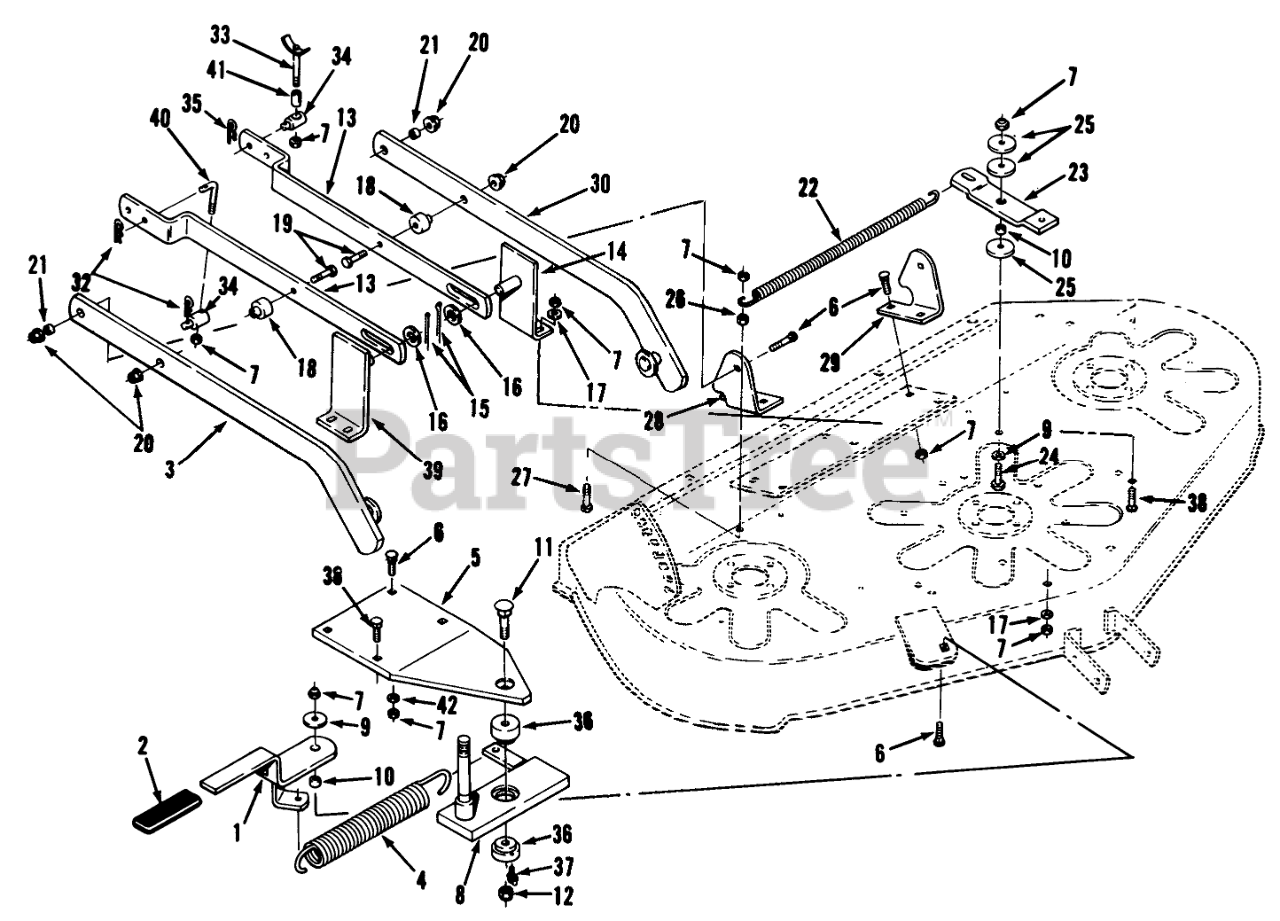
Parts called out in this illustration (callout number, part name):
1	Lever
3	Draft Bar RH
4	Spring
5	Plate
6	Bolt
7	NUT
8	Countershaft
9	WASHER
10	SPACER
11	Bolt
12	Nut
13	Bar-Leveler
14	Bracket
15	PIN-4
16	WASHER
17	Washer
18	SPACER
19	Bolt
20	LOCKNUT-FLANGE
21	SPACER
22	SPRING - EXTENSION
23	Arm-Idler
24	BOLT
25	Washer
26	Nut
27	Bolt
28	Bracket RH
29	Bracket LH
30	Draft Bar LH
32	Cotter Pin
33	WLDMT-HANGER ROD
34	Trunion
35	Hairpin
36	BUSHING
37	Fitting-Grease
38	Bolt
39	Bracket RH
40	ROD-LIFT
41	SPACER .375 ID X 1.6
42	Washer
